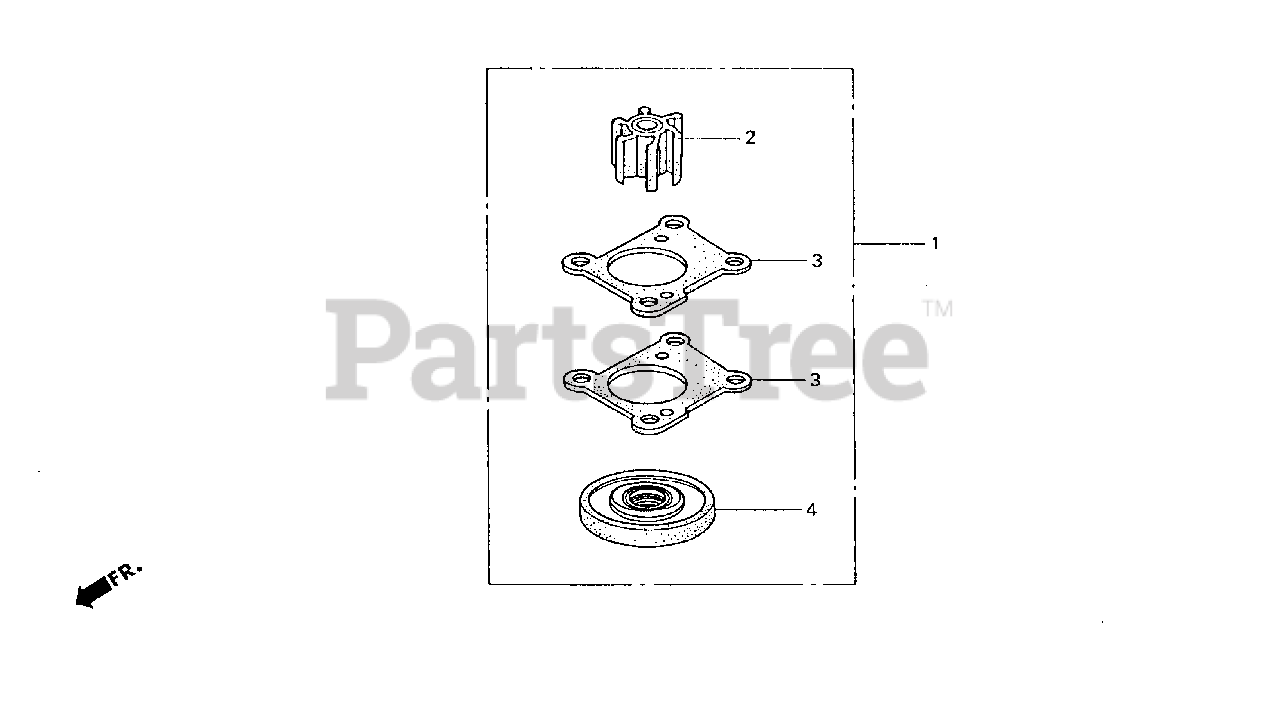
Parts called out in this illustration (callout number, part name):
1	IMPELLER KIT, WATER PUMP
2	IMPELLER, PUMP
3	GASKET, IMPELLER
4	SEAL, WATER (15MM) (NOK)
